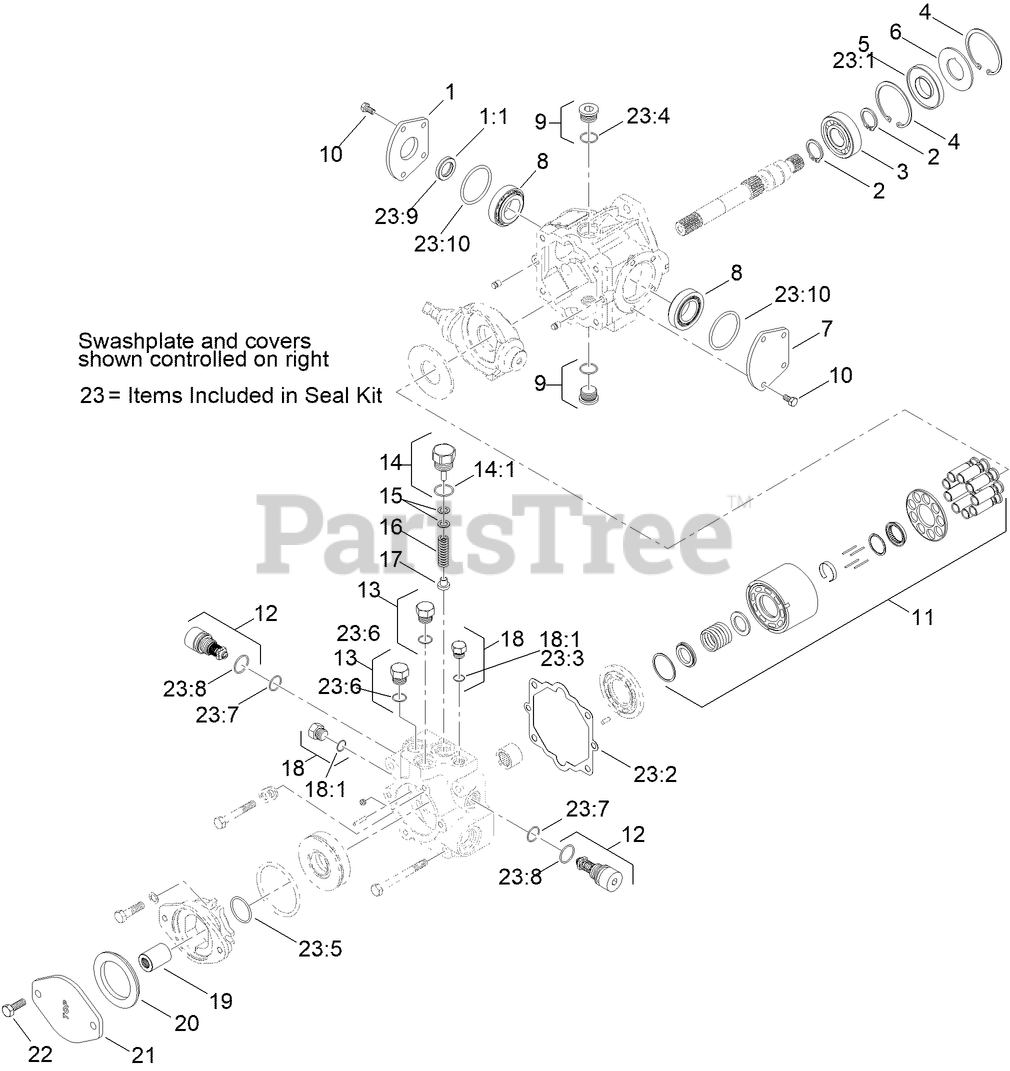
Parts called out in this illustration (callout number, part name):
1	TRUNNION COVER ASM
1:1	SEAL-LIP
2	RING-RETAINING
3	BEARING-BALL
4	RING-RETAINING
5	SEAL-LIP
6	WASHER-BACKUP
7	COVER-TRUNNION
8	BEARING KIT
11	CYLINDER BLOCK KIT
12	VALVE-SOLENOID, CHECK
14	PLUG-RELIEF, CHARGE
14:1	O-RING
15	SHIM KIT
16	SPRING
17	POPPET-RELIEF, CHARGE
18	PLUG ASM
18:1	O-RING
19	COUPLING
20	SEAL-A, PAD
22	SCREW
23	SEAL KIT
23:1	SEAL-LIP
23:2	Gasket-End Cap
23:3	O-RING
23:4	O-RING
23:5	O-RING
23:6	O-RING
23:7	O-RING
23:8	R-RING
23:9	SEAL-LIP
23:10	O-RING
